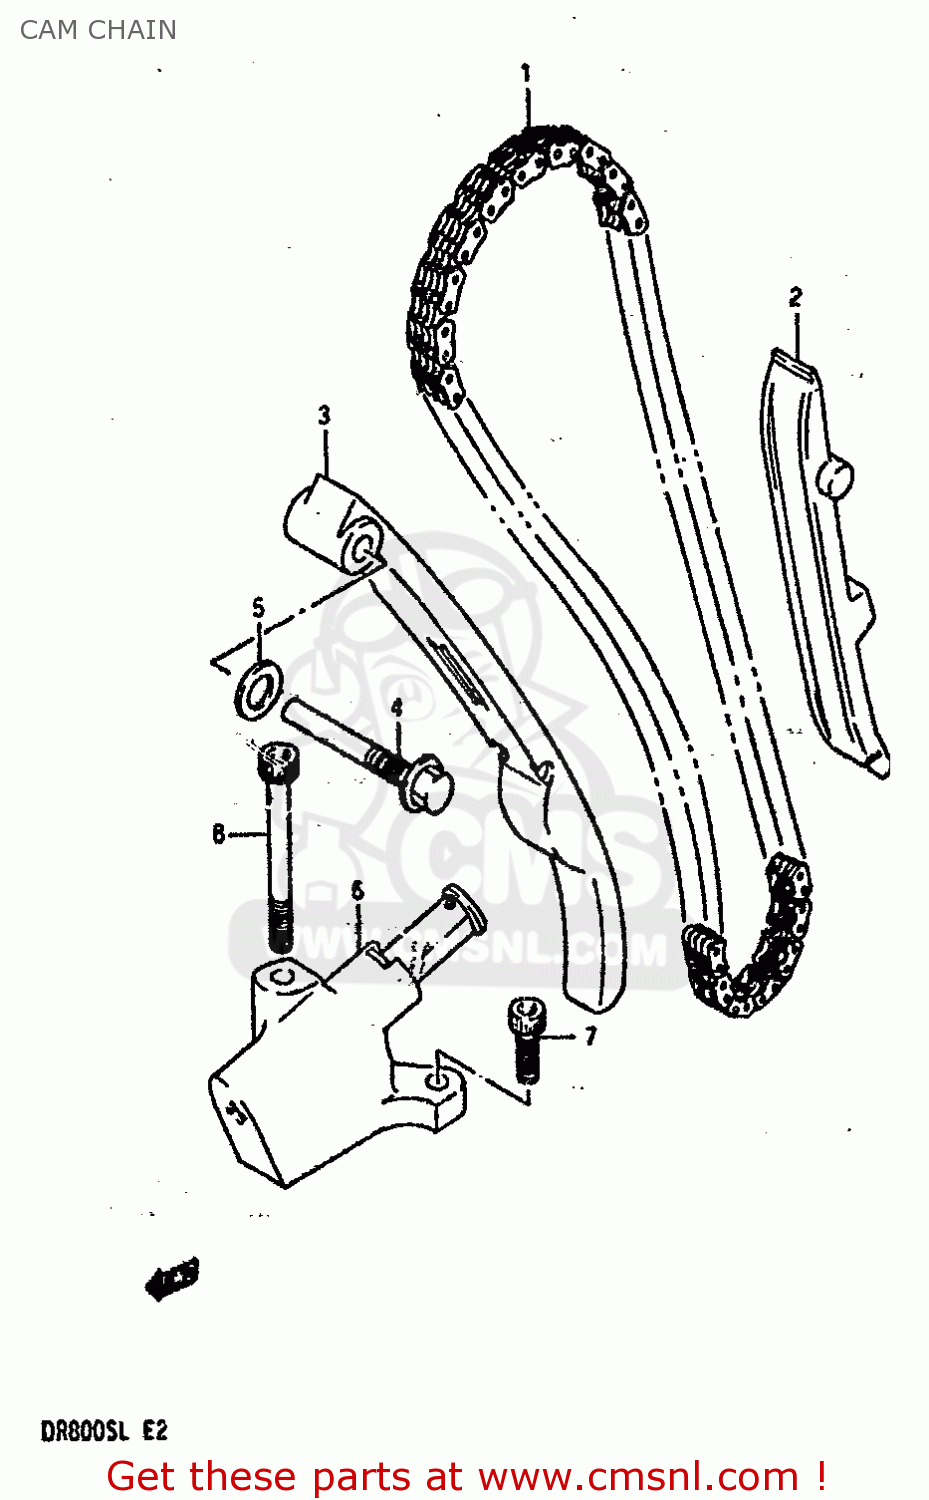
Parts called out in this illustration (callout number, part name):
1	CHAIN,CAMSHAFT DRIVE
2	GUIDE,CAM CHAIN
3	TENSIONER,CAM CHAIN
4	BOLT,CAM CHAIN TENSIONER
5	GASKET 8.2X14X1 (NAS)
6	ADJUSTER ASSY,TENSIONER
7	BOLT
8	BOLT
